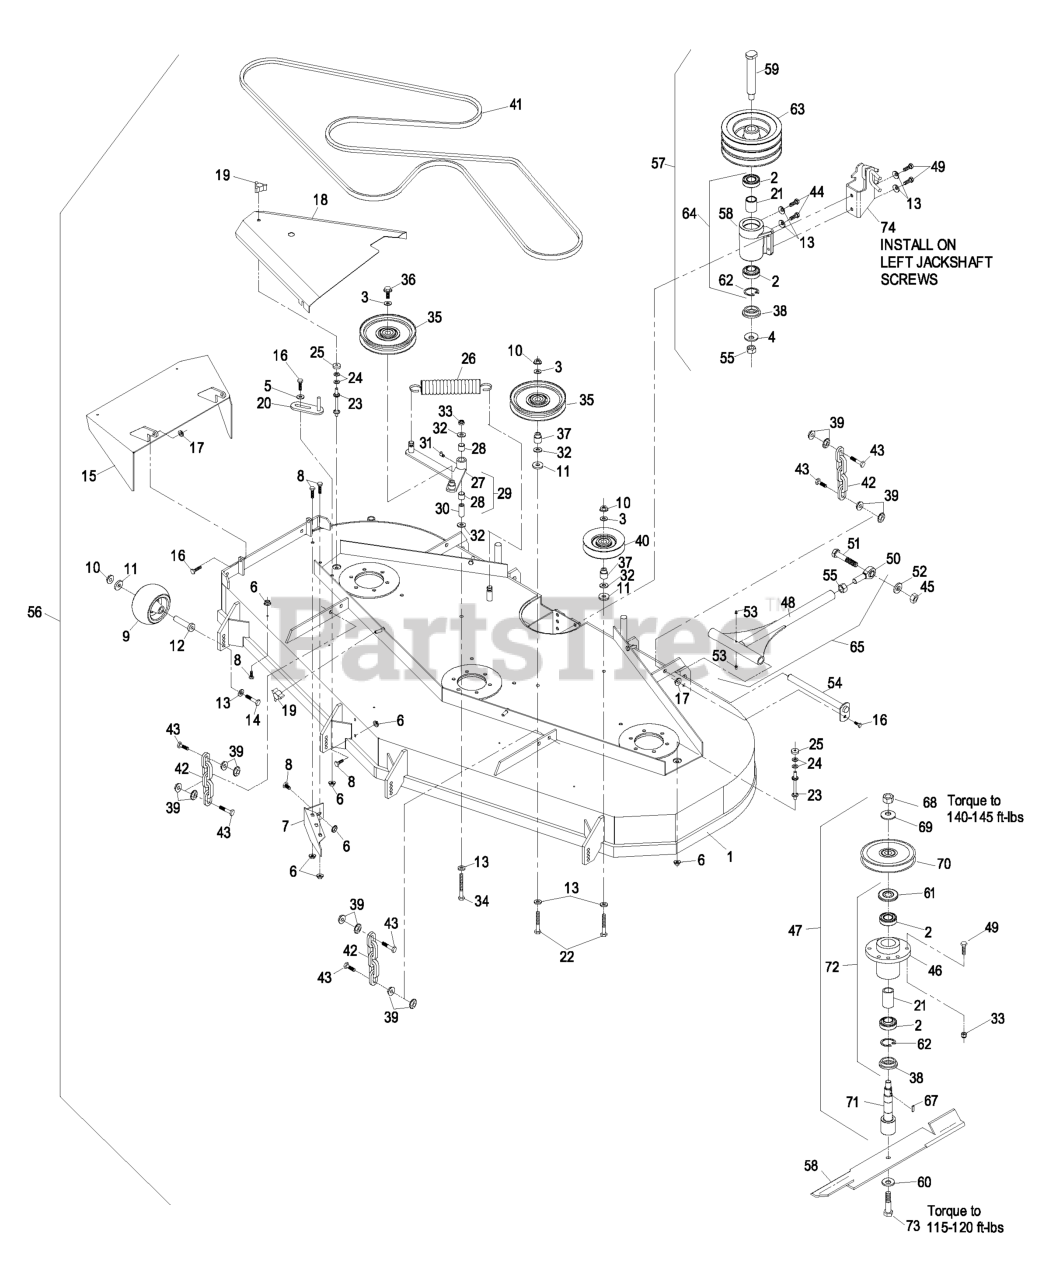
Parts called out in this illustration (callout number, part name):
1	Deck Wldmt, 72
2	BEARING-JACKSHAFT
3	WASHER-FLAT
4	WASHER-SPRING
5	WASHER-SPRING
7	WLD,BAFFLE DISCHARGE
8	SCREW-HH
9	ROLLER-SCALP, ANTI
10	NUT-HHF, WHIZ
12	BUSHING-ROLLER
13	WASHER-BELLEVILLE
14	SCREW-HH
15	WLD,CHUTE 72
16	SCREW-HH
17	NUT-LOCK, NI
18	SHIELD,BELT RH
19	KNOB-3 PRONG
20	GUIDE-BELT
21	SPACER-BEARING
22	SCREW-HH
23	STUD-SHIELD, BELT (SHORT)
24	WASHER-FLAT
28	SLEEVE-BEARING
30	BUSHING
31	FITTING-GREASE, 90 DEG
32	WASHER-FLAT
33	NUT-LOCK, NI
34	SCREW-HH
36	SCREW-HHF
37	BUSHING-IDLER
38	SPACER-GUARD, BOTTOM
40	PULLEY-IDLER
41	BELT-V
42	CHAIN-LIFT, DECK
43	SCREW-HH
44	SCREW-HH
45	NUT-HEX
49	SCREW-HH
50	BALLJOINT-SPHERICAL
51	SCREW-HH
52	WASHER-LOCK
53	FITTING-GREASE
54	PIN-STRUT
55	NUT-HEX
56	Complete Deck Assy
57	ASM,JACKSHAFT
59	JACKSHAFT,LAZER XP
60	WASHER-BLADE BOLT, HEAVY
61	GUARD-BEARING, TOP
62	RING-SNAP
65	STRUT WLDMT S/A
70	SHEAVE,BLADE DRIVE 7.5
71	SPINDLE,SHORT
73	SCREW-CAP
